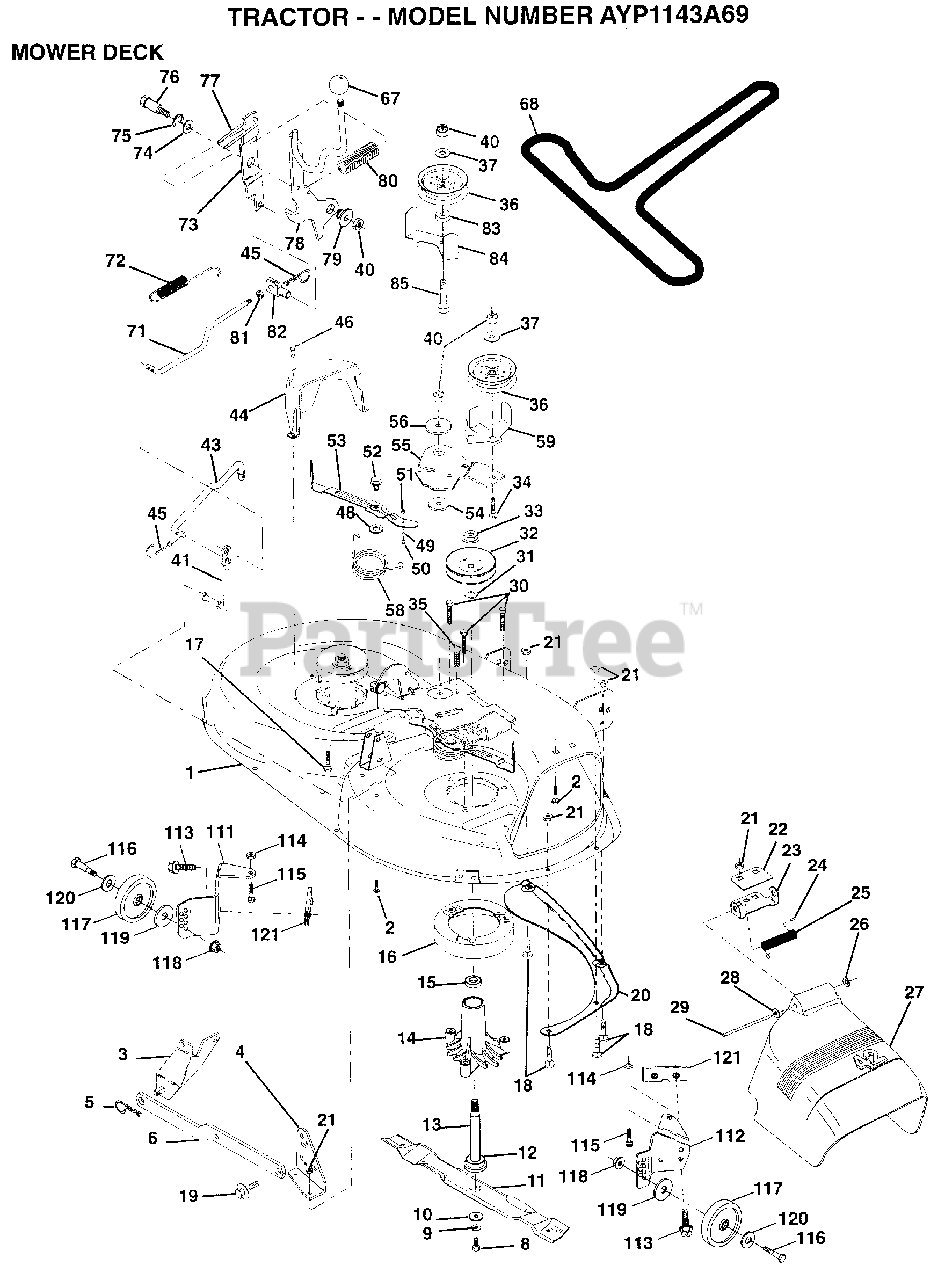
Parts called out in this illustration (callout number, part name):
1	DECK.WELD.42.
2	BOLT
3	BRKT ASM SWAY BAR
4	BRKT DECK SW BAR
8	BLADE BOLT
10	WASHER.HARD.BLADE
11	"BLADE.42"" MULCHER"
12	BEARING.BALL
14	HSG ASM MANDREL
14	STRIPPER RND MWR
15	BEARING
17	BOLT RDHD 3/8-16
18	BOLT
19	BOLT SHD 5/16-18
22	STIFFENER BRKT
23	DEFLECTOR BRKT
24	CAP-SLEEVE LT
25	SPRING TORSION
26	NUT PUSH M
27	DEFLECTOR.SHIELD
28	WASHER
29	HINGE ROD
31	WASHER
34	BOLT
35	XMAS TREE FASTNER
36	FLAT IDLER PULLEY
37	WASHER
41	PIVOT ROD
43	ROD CLUTCH W/NIBS
44	GUARD MAND LH BLK
45	RETAINER M
46	SCREW.1/4-20X5/8
48	HARD SMALL WASHER
50	SHOULDER BOLT
51	LOCKNUT
52	BOLT.SHLD.5/16-18
53	BRAKE PAD ARM ASM
54	HARDENED WASHER
56	SPACER RETAINER
58	SPRING TORSN BRAK
59	GUARD IDLER TUV
67	KNOB T (1/2-HOLE)
68	BELT.V.T-PATH
71	ROD CLUTCH 38/42
72	RETURN SPRING
73	CLUTCH ARM SECOND
74	WASHER
75	RING
76	SHOULDER BOLT
77	SPRING KEEPER
79	BUSHING
81	NUT
82	TRUNION ADJ
83	WASHER
85	BOLT RDHD 3/8-16
113	SCREW
116	BOLT M
117	WHEEL.GAGE.BLK.PL
118	LOCKNUT
119	WASHER
120	WASHER
121	BRACKET.EXTRD.GWL
